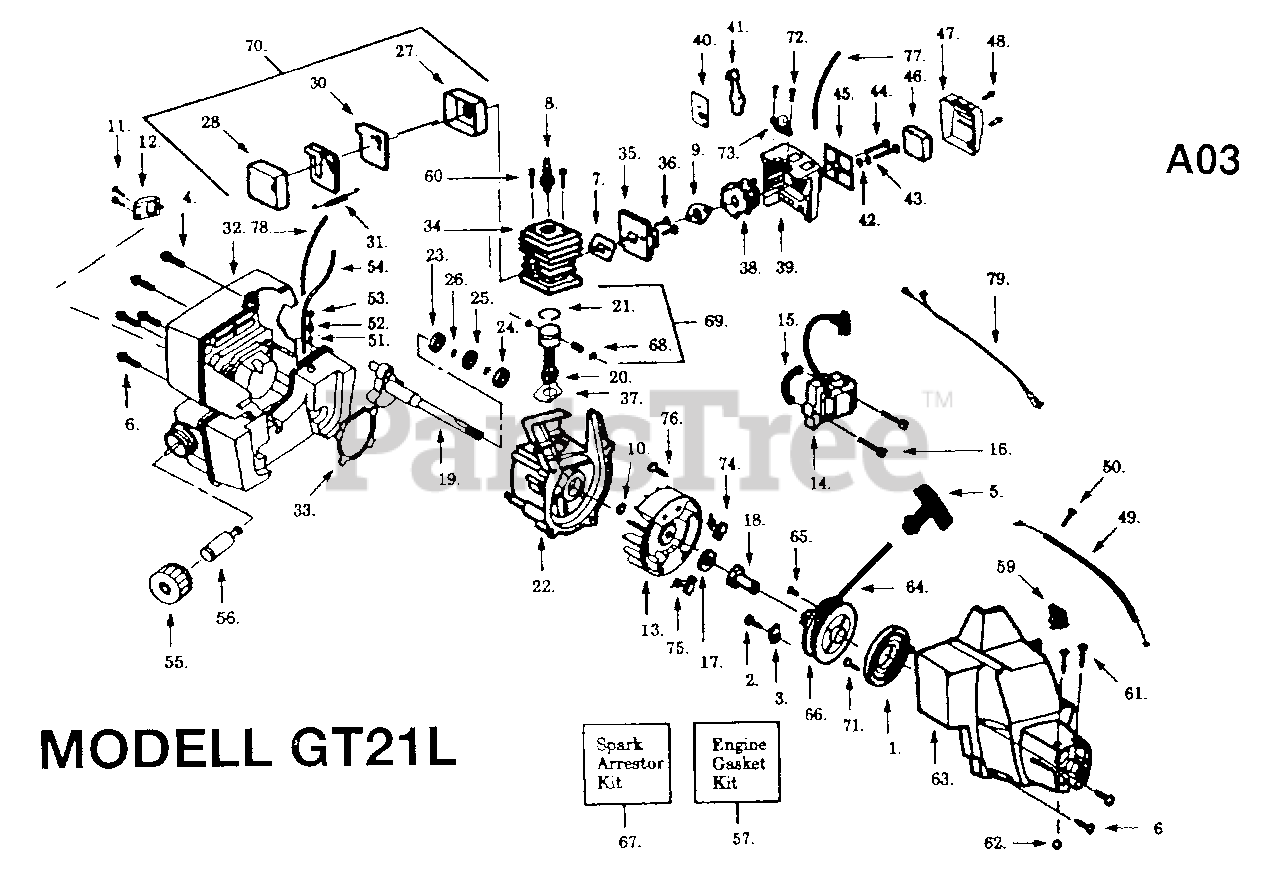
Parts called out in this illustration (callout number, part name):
1	SPRING-STARTER
2	SCREW 8-16 X 9/16 (PLAS
5	HANDLE-STARTER
6	SCREW - SHROUD
7	GASKET
8	SPARK PLUG CJ8 NLA
9	GASKET - CARBURETOR
11	SCREW-8-18 X 5/18(RECES
12	MUFFLER GUARD
13	FLYWHEEL
14	IGNITION MODULE
15	SPACER - IGNITION MODULE
17	WASHER FLAT
18	COUPLING-DRIVE
19	CRANKSHAFT ASSEMBLY
20	CONNECTING ROD ASSEMBLY
21	PISTON RING
22	CRANKCASE ASSY
23	BEARING
25	SEALING RING
26	RETAINING RING
27	MUFFLER BODY
28	MUFFLER COVER
30	MUFFLER BAFFLE - FIRST
31	MUFFLER SPRING
33	GASKET, CRANKCASE
34	CYLINDER
35	REPL BY 530 04 76-59
36	SCREW - CARB. ADAPTOR
37	GASKET - CYLINDER
38	CARBURETOR
40	CHOKE PLATE
41	CHOKE SHUTTER
43	CHOKE SPACER
45	FILTER PLATE
46	AIR FILTER FOAM
47	AIR FILTER COVER
48	SCREW - THROTTLE HOUSING
49	THROTTLE CABLE
51	VALVE-CHECK (DUCKBILL)
55	CAP ASSY W/ RETAINER
56	FUEL PICK UP ASSY
59	REPL BY 530 06 95-72
61	SCREW - PINCH CLAMP
62	LOCKNUT-HEX 10-24
66	STARTER PULLEY KIT
67	KIT-SPARK ARRESTOR (OLD STYLE)
68	WRIST PIN RET.
69	PISTON KIT
70	MUFFLER KIT
72	SCREW - PRIMER ASSEMBLY
73	PRIMER BULB ASSEMBLY
74	STARTER DOG SPRING
75	MUFFLER SPRING
78	FUEL LINE - PRIM/TNK
79	LEAD WIRE ASSEMBLY
